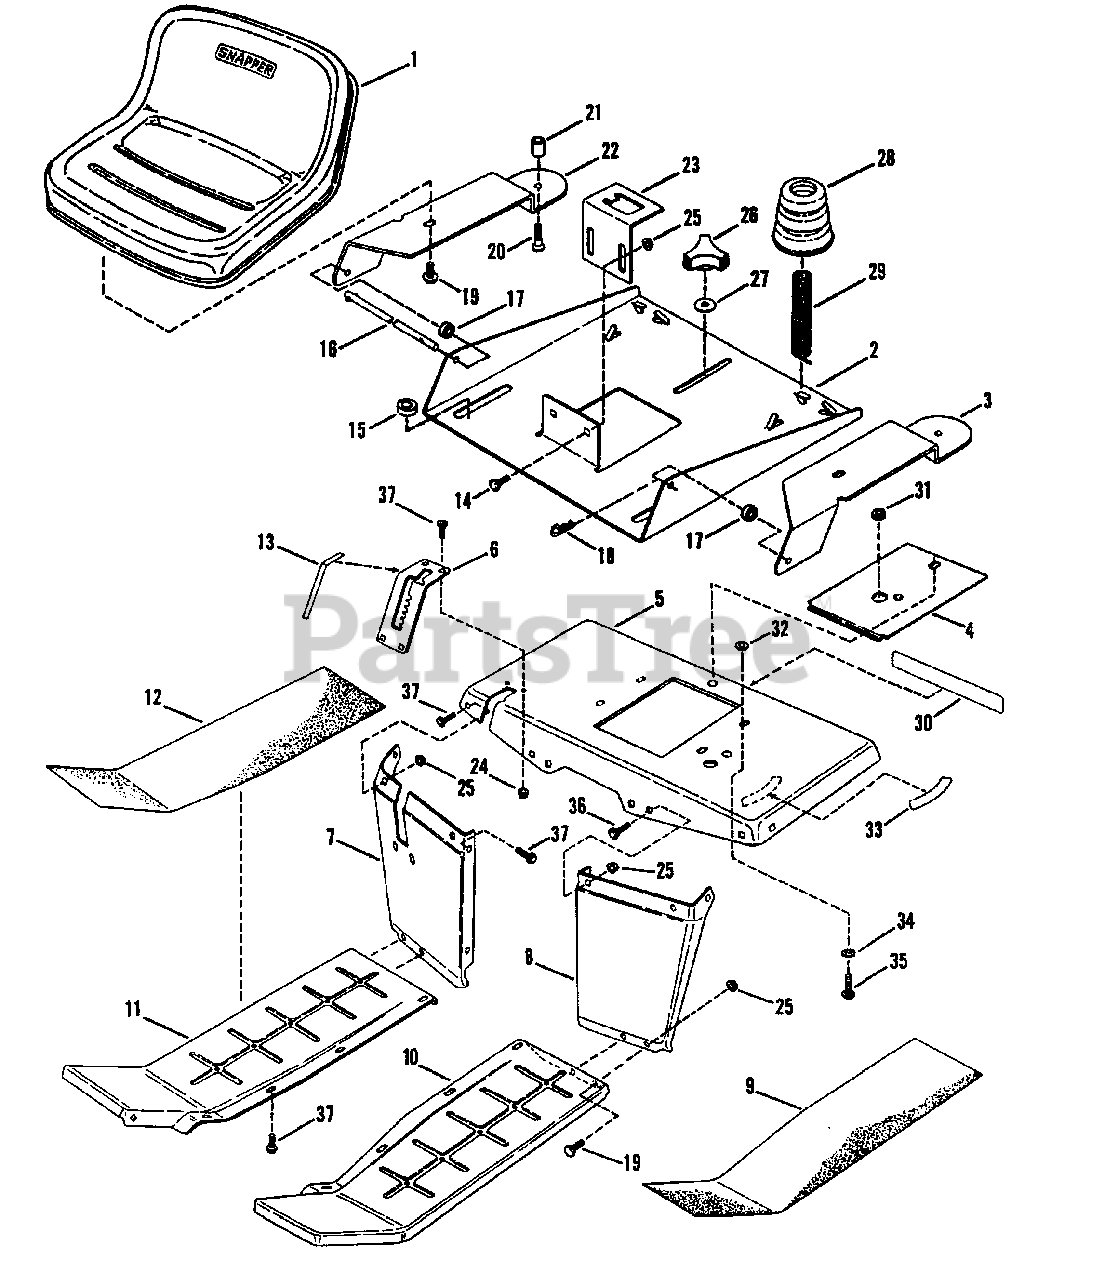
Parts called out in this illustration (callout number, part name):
1	SEAT, Operator's
2	SUPPORT, Seat
3	BRACKET, Seat Support, L.H.
4	COVER, Access
5	FENDER, Rear
6	DETENT, Shift
7	EXTENSION, Right Side Fender
8	EXTENSION, Left Side Fender
9	TREAD, Left Side (Non-Skid)
10	PANEL, Left Side Step
11	PANEL, Right Side Step
12	TREAD, Right Side (Non-Skid)
13	DECAL, Speed Shift
14	BOLT, 5/16-18 x 5/8" Short Neck Carriage, Grade 5
15	SPACER
16	ROD, Seat Hinge
18	PIN, Hair
19	BOLT, 5/16-18 x 1/2" Hex Flange Lock, Grade 5
20	SCREW, 5/16-18 x 1" Flat Head Hex Recess
22	BRACKET, Seat Support, R.H.
23	BRACKET, Switch
24	NUT, 1/4-20 Hex Flange Lock
25	NUT, 5/16-18 Hex Flange Lock
26	KNOB, Seat Adjustment
27	WASHER, 5/16 I.D. x 1" O.D. Flat
28	CUSHION, Seat
29	SPRING
30	DECAL, Snapper
31	GROMMET, Split
32	WASHER, 5/16" x 1-1/4" x 3/32" Flat
33	DECAL, Hi-Low Range (Shift)
34	RETAINER, Bolt
35	BOLT, 5/16-18 x 1" Square Neck Carriage
36	BOLT, 5/16-18 x 1/2" Short Neck Carriage, Grade 5
37	SCREW, 5/16-18 x 5/8" Self-Tap
